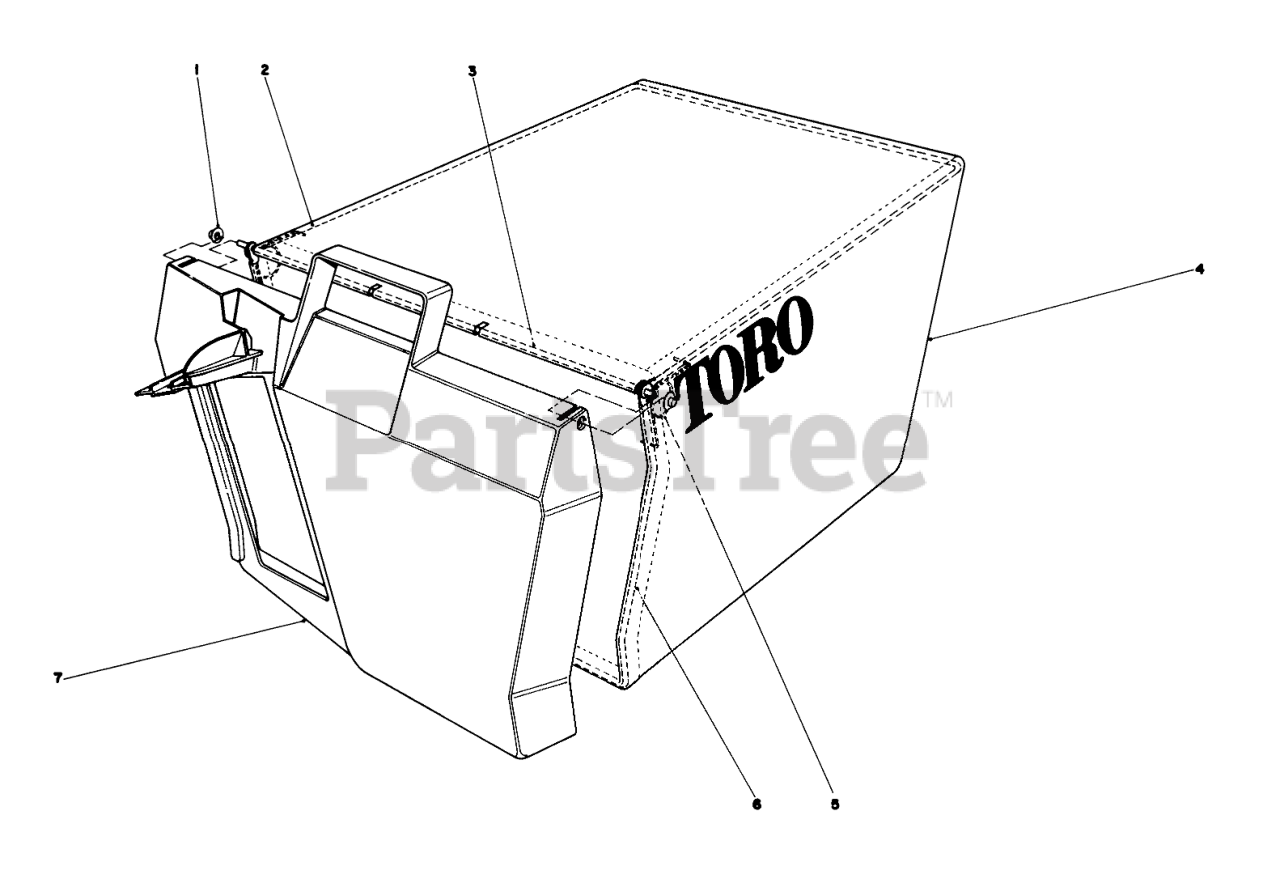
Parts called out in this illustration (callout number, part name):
1	NUT-PUSH
2	Bag Frame Upper
3	HINGE-DOOR, BAG
4	Grass Bag
5	SPRING
6	Frame Bag
7	Door Grass Bag
